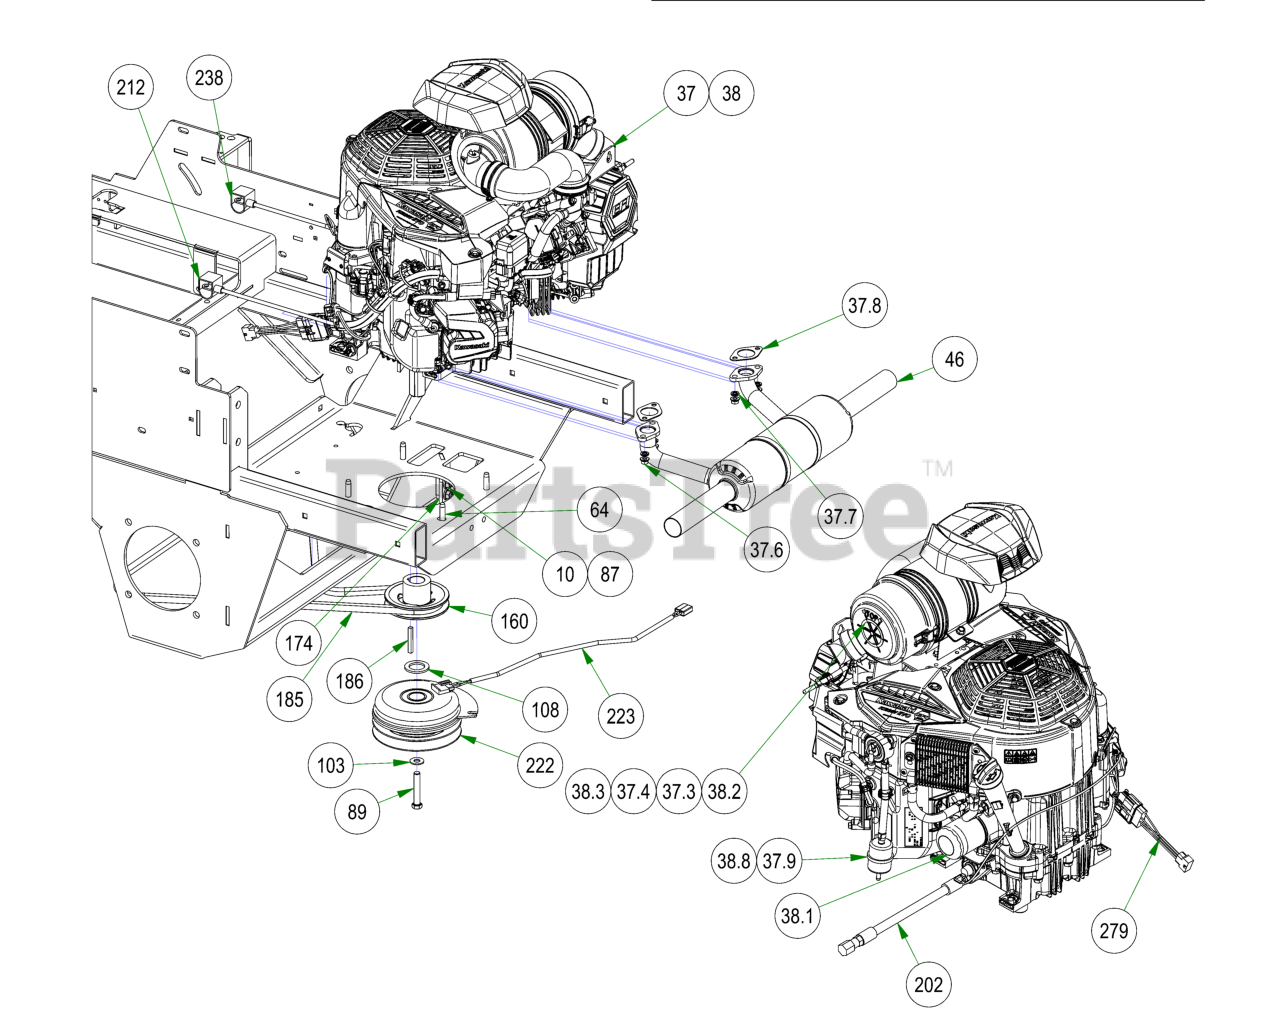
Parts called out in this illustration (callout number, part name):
10	3/8-16 NYLON INSERT FLANGE LOCKNUT (GR.F) ZINC
37	KAWASAKI EVO EFI 31HP
37.2	Oil Filter
37.3	Inner Air Filter
37.4	Outter Air Filter
37.5	Spark Plug - Kawasaki
37.6	Exhaust Nut
37.7	Exhaust Lock Washer
37.8	Kawasaki EVO Exhaust Gasket
37.9	FUEL FILTER
38	KAWASAKI EVO EFI 34HP
38.2	Inner Air Filter
38.3	Outter Air Filter
38.4	Spark Plug - Kawasaki
38.5	Exhaust Nut
38.6	Exhaust Lock Washer
38.7	Kawasaki EVO Exhaust Gasket
38.8	Universal Inline Fuel Filter
46	Rebel Kawasaki EVO Muffler
64	3/8-16 X 1-1/2HEX WASHER UNSLOT SERRATED
87	3/8-16 X 1 CARRIAGE BOLT (GR.5) ZINC
89	7/16-20 X 2-1/2 HEX Bolt GR 8 W/ Patch
103	3/8 FLAT WASHER USS (1" OD) ZINC
108	1.140 ID X 1.750 OD X .132 THICK FLAT WASHER PLAIN
160	4 3/4 Motor Pulley
174	Rebel Clutch Tab
185	2019 Rebel Pump Belt
186	1/4 X 2 SQ MACHINERY KEY 1018 STL PLAIN
202	Kawasaki Oil Drain
212	14" Red Battery Cable-Base Outlaw
222	Clutch Assembly
223	Clutch Pigtail
224	2023 Rebel Frame - Painted
238	Starter Cable
279	Harness Adaptor for Kawasaki EFI
